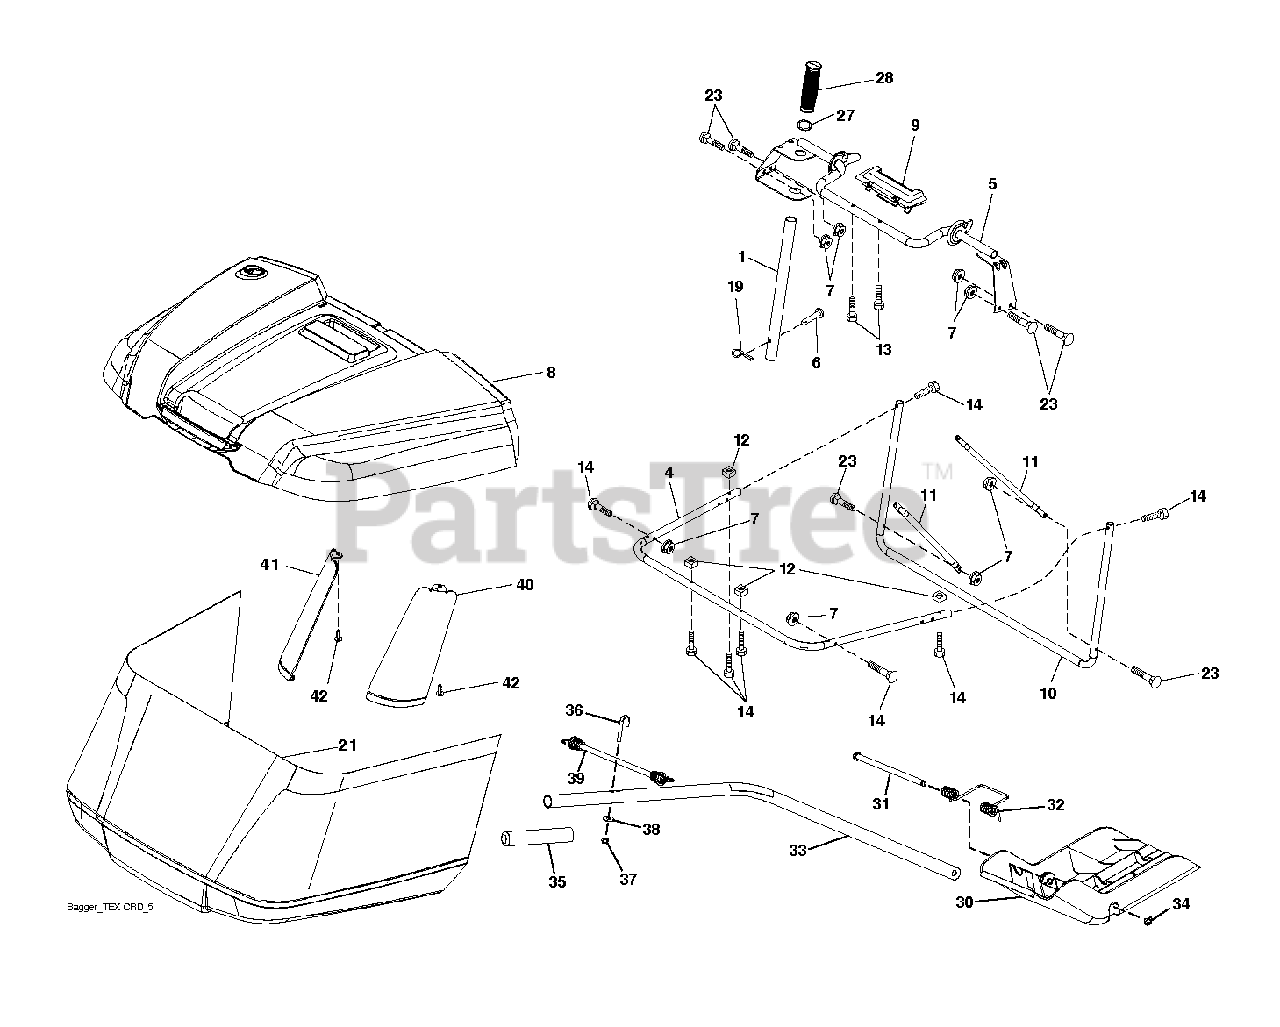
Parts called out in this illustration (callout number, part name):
1	TUBE.PNT.HDL.BAGGER.
6	RIVET,DRILLED
7	NUT T
19	PIN.COTTER.5/16.BOW TI
28	GRIP.HANDLE.BLACK
34	E-RING.5/16"
38	WASHER
